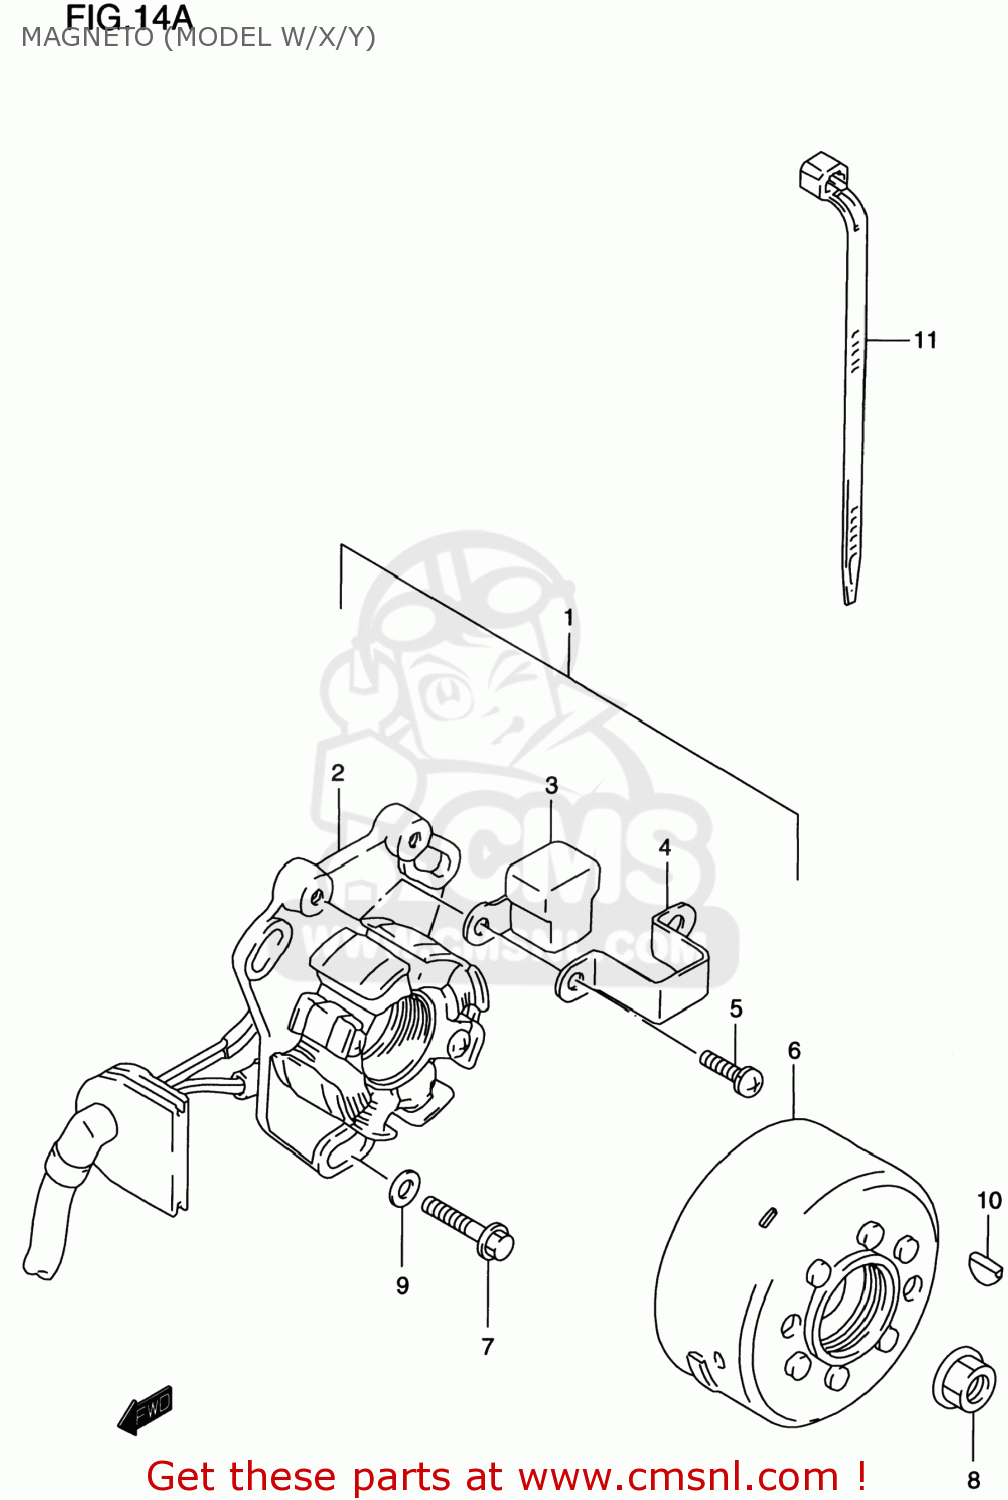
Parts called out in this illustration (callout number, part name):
1	MAGNETO ASSEMBLY
2	STARTER ASSY
3	COIL,PULSER
4	HOLDER,PICK UP COIL
5	SCREW
6	ROTOR ASSY
7	SCREW
8	NUT
9	WASHER
10	KEY
11	CLAMP(L:235)
